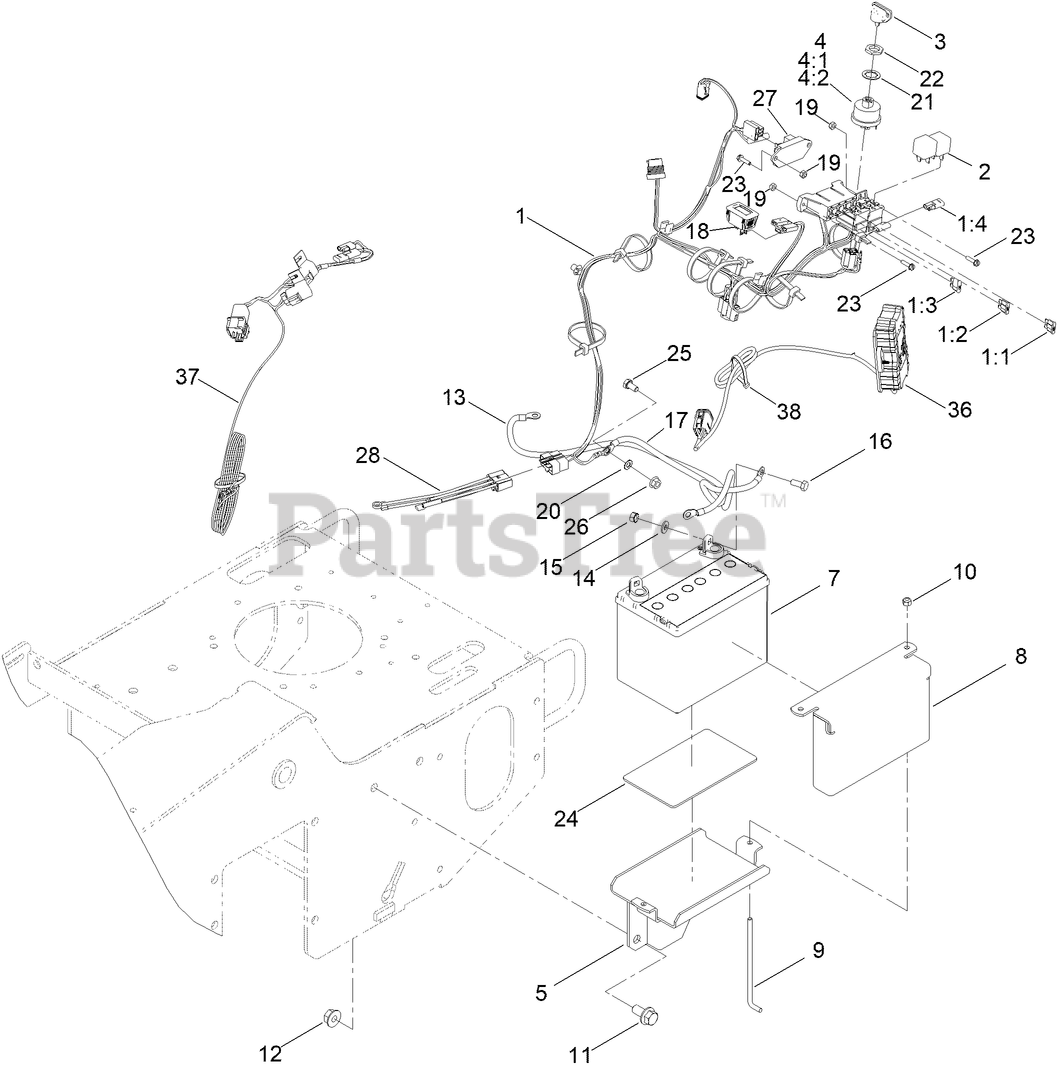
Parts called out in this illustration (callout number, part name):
1	HARNESS-WIRE
1:1	FUSE-BLADE, 30 AMP
1:2	FUSE-BLADE, 25 AMP
1:3	FUSE-BLADE, 20 AMP
1:4	CAP-PLUG
2	RELAY
3	KEY-IGNITION
4:1	WASHER-LOCK
4:2	NUT-HH
5	TRAY-BATTERY
8	PLATE-HOLD DOWN, BATTERY
9	HOLDOWN-BATTERY
10	NUT-LOCK, NI
11	SCREW-HHF
12	NUT-HHF
13	CABLE-BATTERY, POSITIVE
14	WASHER-FLAT
15	NUT-KEPS
16	SCREW-HH
17	CABLE-BATTERY, BLACK
18	HOURMETER
19	NUT-LOCK, NI
20	WASHER-LOCK
23	SCREW-HWH
24	PAD-SKID, ANTI
25	SCREW-HH
26	NUT-HF
27	MODULE-DELAY
28	HARNESS
36	M7L-LITE ZTR KIT ASM
37	HARNESS-WIRE, MACHINE ZTR
38	TIE-CABLE
